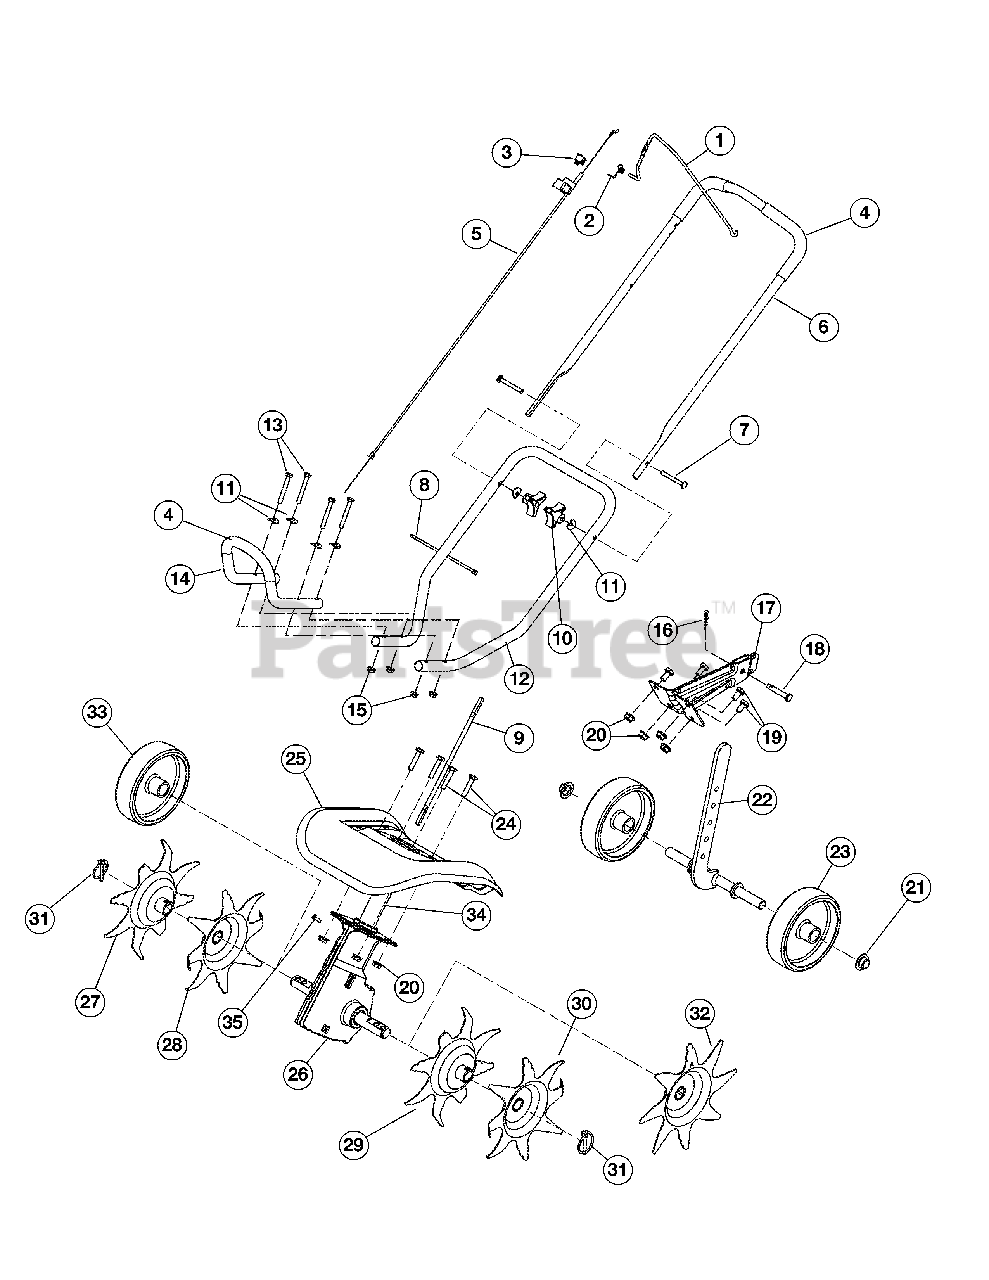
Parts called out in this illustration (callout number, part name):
1	Throttle Control
2	Torsion Spring
3	On/Off Switch
4	Foam Grip
5	Throttle Cable
6	Upper Handle
8	Cable Tie
9	Flex Shaft
11	Shoulder Washer
12	Lower Handle
13	Screw
14	Front Handle
15	Lock Nut
16	Cotter Pin
17	Tailpiece Bracket Assembly
18	Clevis Pin
19	Cap Screw
20	Lock Nut
21	Cap Push
22	Wheel Support Bracket Assembly
23	Wheel
24	Cap Screw
25	Tine Shield
26	Gear Box Assembly
27	Tine
28	Tine
29	Tine
30	Tine
32	Edger Tine
33	Edger Wheel
34	Drive Shaft Housing
35	Sleeve Retaining Bolt
